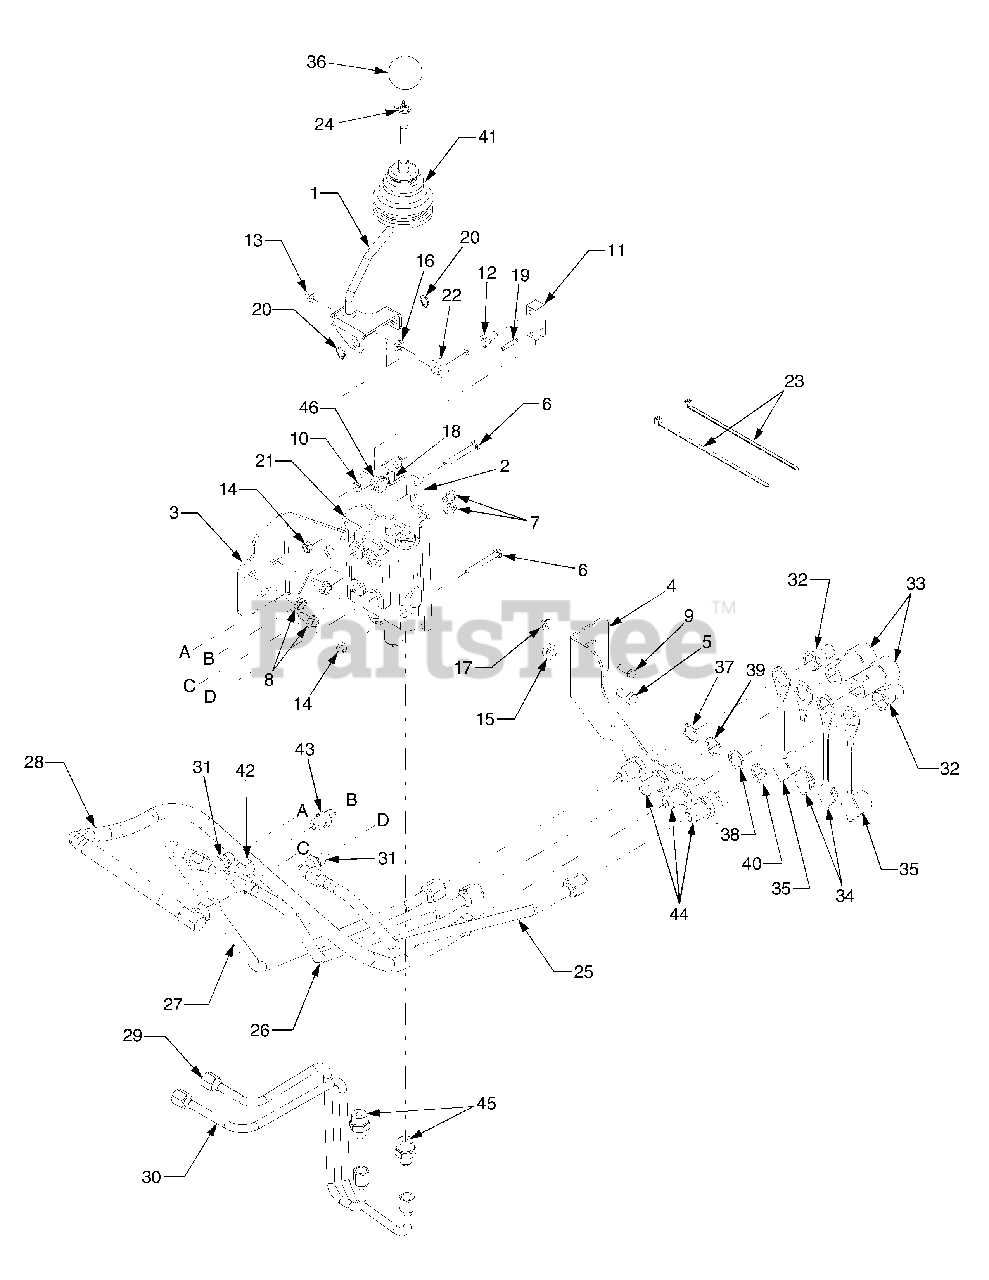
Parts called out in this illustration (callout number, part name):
1	Handle Assembly, Valve
2	Bracket Assembly,Pivot
3	Bracket, Valve Mounting
4	Bracket, Fitting Mount
5	Screw, Hex Cap, 3/8-16 x .75 GR5
6	Screw, Hex Cap , 1/4-20, 2.00, Gr5
7	Screw, Hex Wash. Hd. Tapp 1/4-20 x .50
8	Screw, Hex Wash. Hd. Tapp 5/16-18 x .75
9	Screw, Hex Cap 1/4-20 x .75 GR5
10	Shaft, Valve Pivot
11	Link, Valve Spool
12	Stud, Ball Joint Pivot
13	Nut, Hex Lock, 5/16-24
14	Nut, Hex Nylon Lock, 1/4-20, Gr8
15	Nut, Hex Flange Lock, 3/8-16
16	Nut, Jam, 5/16-24, Gr5
17	Nut, Hex Flange Lock, 1/4-20
18	Link, Chain
19	Pin, Spirol, 3/16 x 1.0
20	Ring, Snap
21	Valve, Control
22	Ball Joint, .3125 Id x 5/16-24
23	Tie, Cable
24	Clamp, Hose
25	Tube, Hydraulic - Bucket Return .
26	Tube, Hydraulic - Bucket Lift
27	Tube, Hydraulic - Boom Lift
28	Hose, Hydraulic - Boom Return
29	Tube, Hydraulic - Valve Return
30	Tube, Valve Inlet
31	Fitting, 90° 6-6 Orb
32	Coupling, Male Hydraulic, 3/8-18
33	Coupling, Female Hydr. 3/8-18
34	Plug, Hydraulic Coupler - Male
35	Plug, Hydraulic Coupler - Female
36	Knob, 1.625 Dia x 3/8-16 Thd
37	Washer, Indicator - Red
38	Washer, Indicator - Yellow
39	Washer, Indicator - Green
40	Washer, Indicator - Blue
41	Joystick Boot
42	Fitting, 90 Degree, 6 -6 Swivel
43	Fitting, Straight - 6 Orb
44	Fitting, Bulkhead 3/4-16 x 3/8-18
45	Fitting, Straight - 6 -8 Orb
46	Spacer, .34 ID x .5 OD x .31
